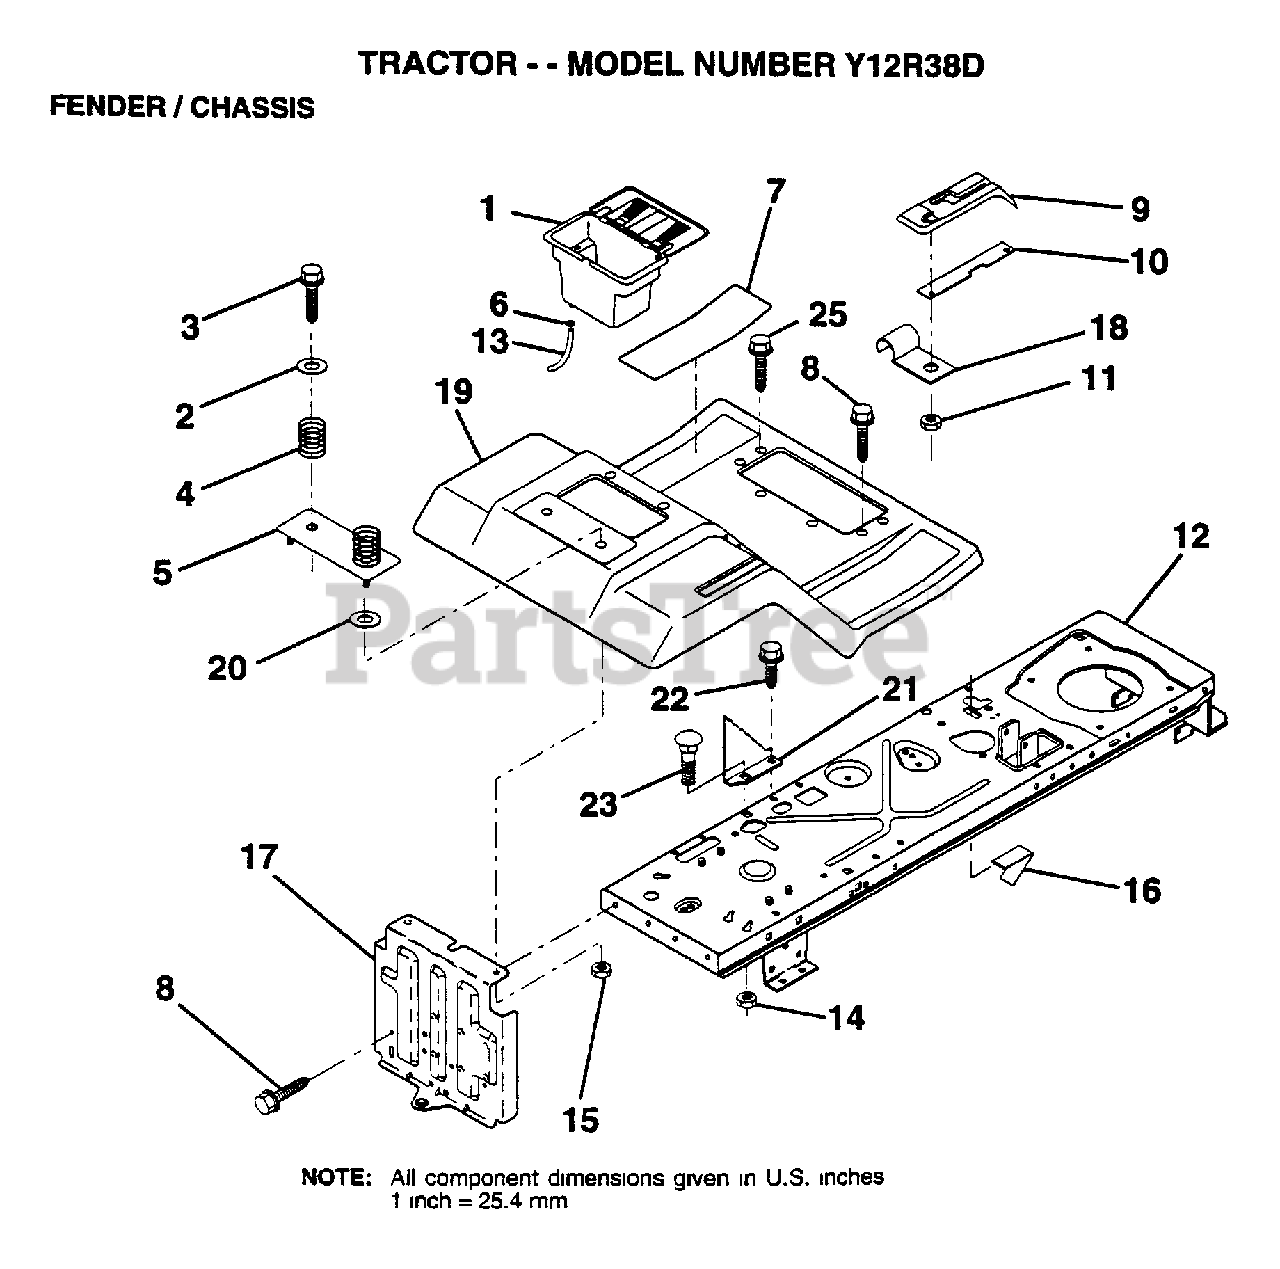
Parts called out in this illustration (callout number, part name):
2	WASHER
3	SCREW
4	SPRING COMPRESSIO
5	BTRY FENDER PLATE
6	HOSE CLAMP T
7	PAD FOOTREST
8	SCREW
10	PLATE LOCK SHIFT
11	NUT
12	CHASSIS.WELD.ASM.
13	TUBE T
15	NUT HXKEP 1/4X20
17	DRAWBAR ASM LR
18	"CLIP,INSULATOR"
19	FENDER/FOOT MS505
21	BRACKET STOP DEPT
22	SCREW LT
25	SCREW
